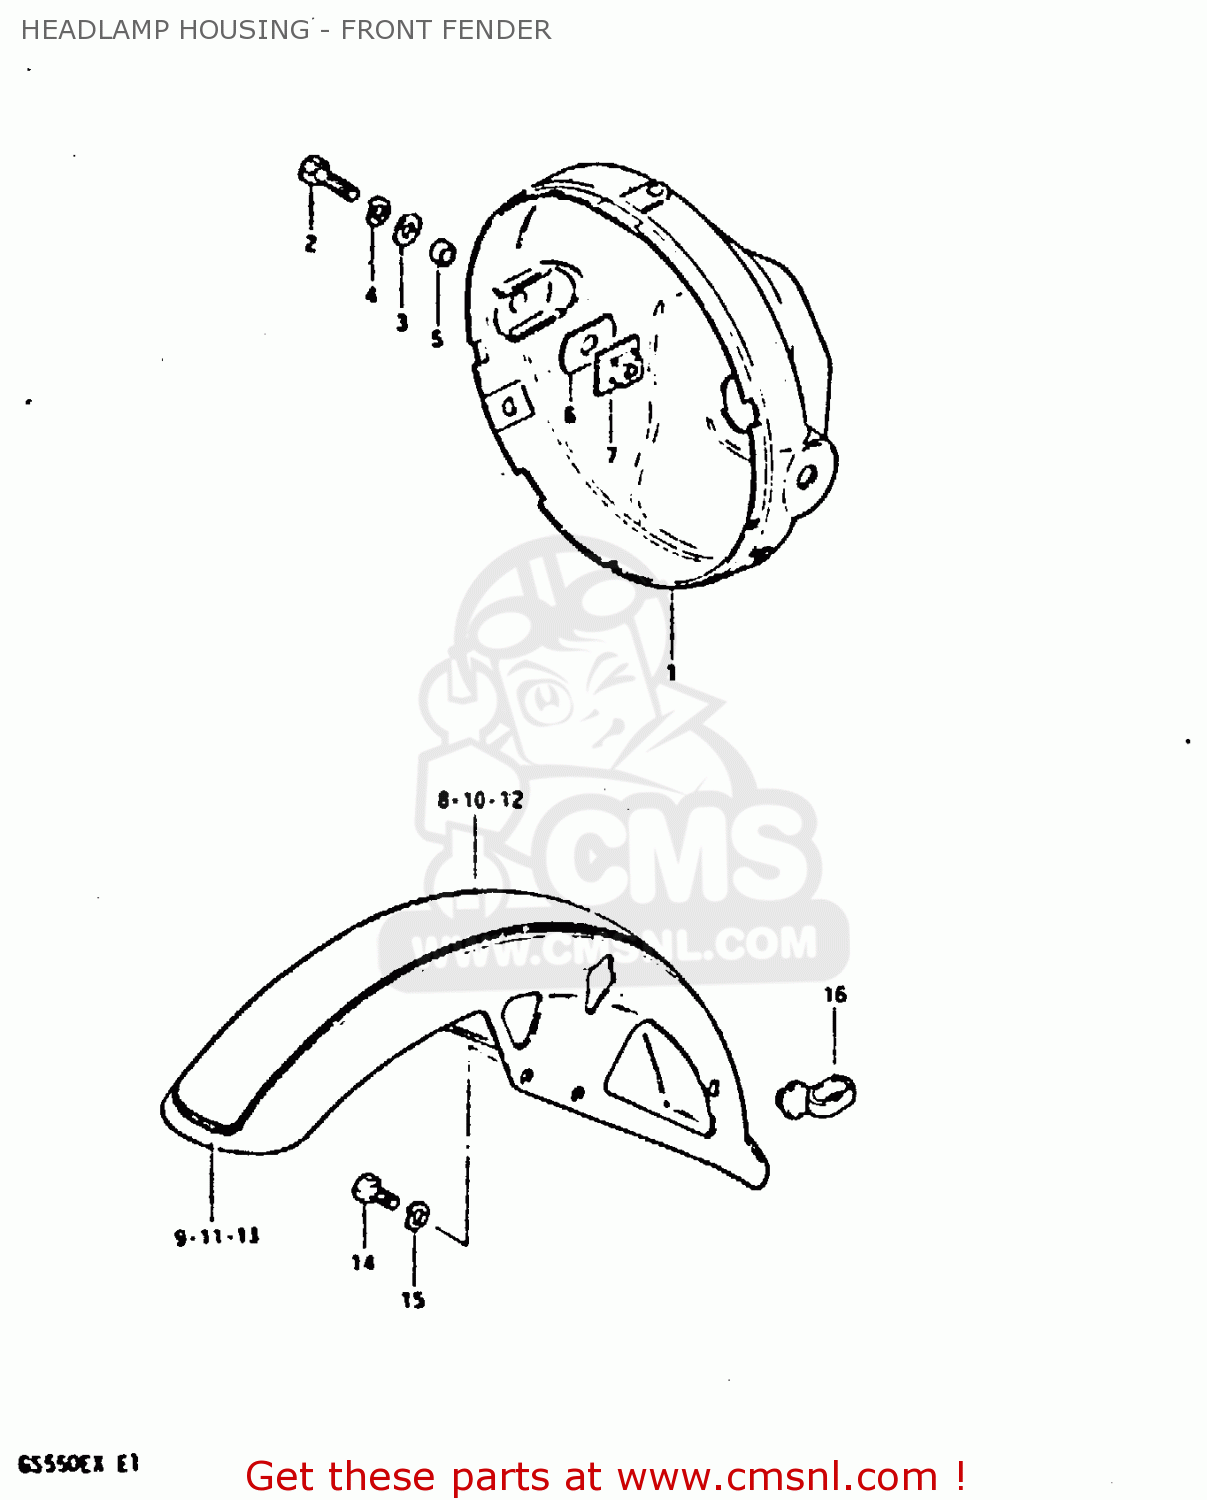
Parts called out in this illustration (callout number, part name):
1	HOUSING,HEADLAMP
2	BOLT
3	WASHER
4	LOCK WASHER
5	SPACER (8.8X12X7)
6	CUSHION
7	PLATE,HEADLAMP HOUSING
8	FENDER, FRONT
9	TAPE
10	FENDER, FRONT (RED)
11	TAPE,FRONT FENDER
12	FENDER, FRONT
13	TAPE
14	BOLT
15	LOCK WASHER
16	GUIDE,CABLE
